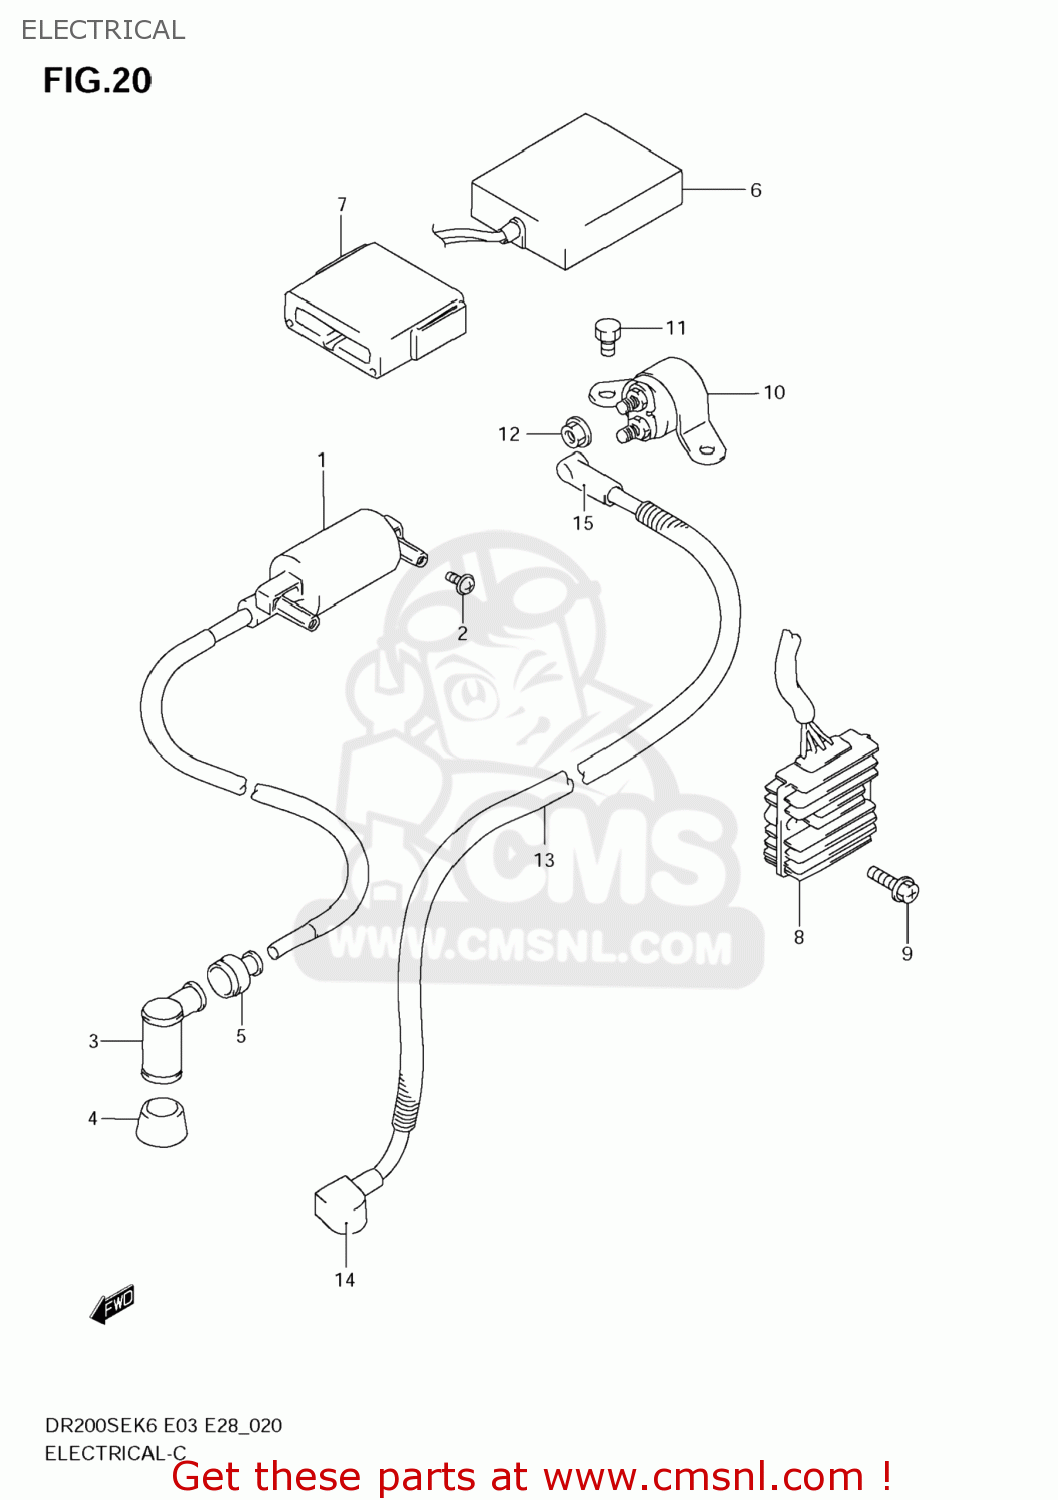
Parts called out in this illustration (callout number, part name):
1	COIL ASSY,IGNITION
2	SCREW
3	CAP ASSY,SPARK PLUG
4	SEAL,SPARK PLUG
5	SEAL,HIGH TENSION CORD
6	IGNITOR
7	CUSHION,CDI UNIT
8	RECTIFIER ASSY
9	SCREW
10	RELAY ASSY,STARTING MOTOR
11	SCREW(6X10)
12	NUT
13	WIRE,STARTER MOTOR LEAD
14	CAP,STARTER MOTOR TERMINAL
15	CAP,STARTER RELAY
